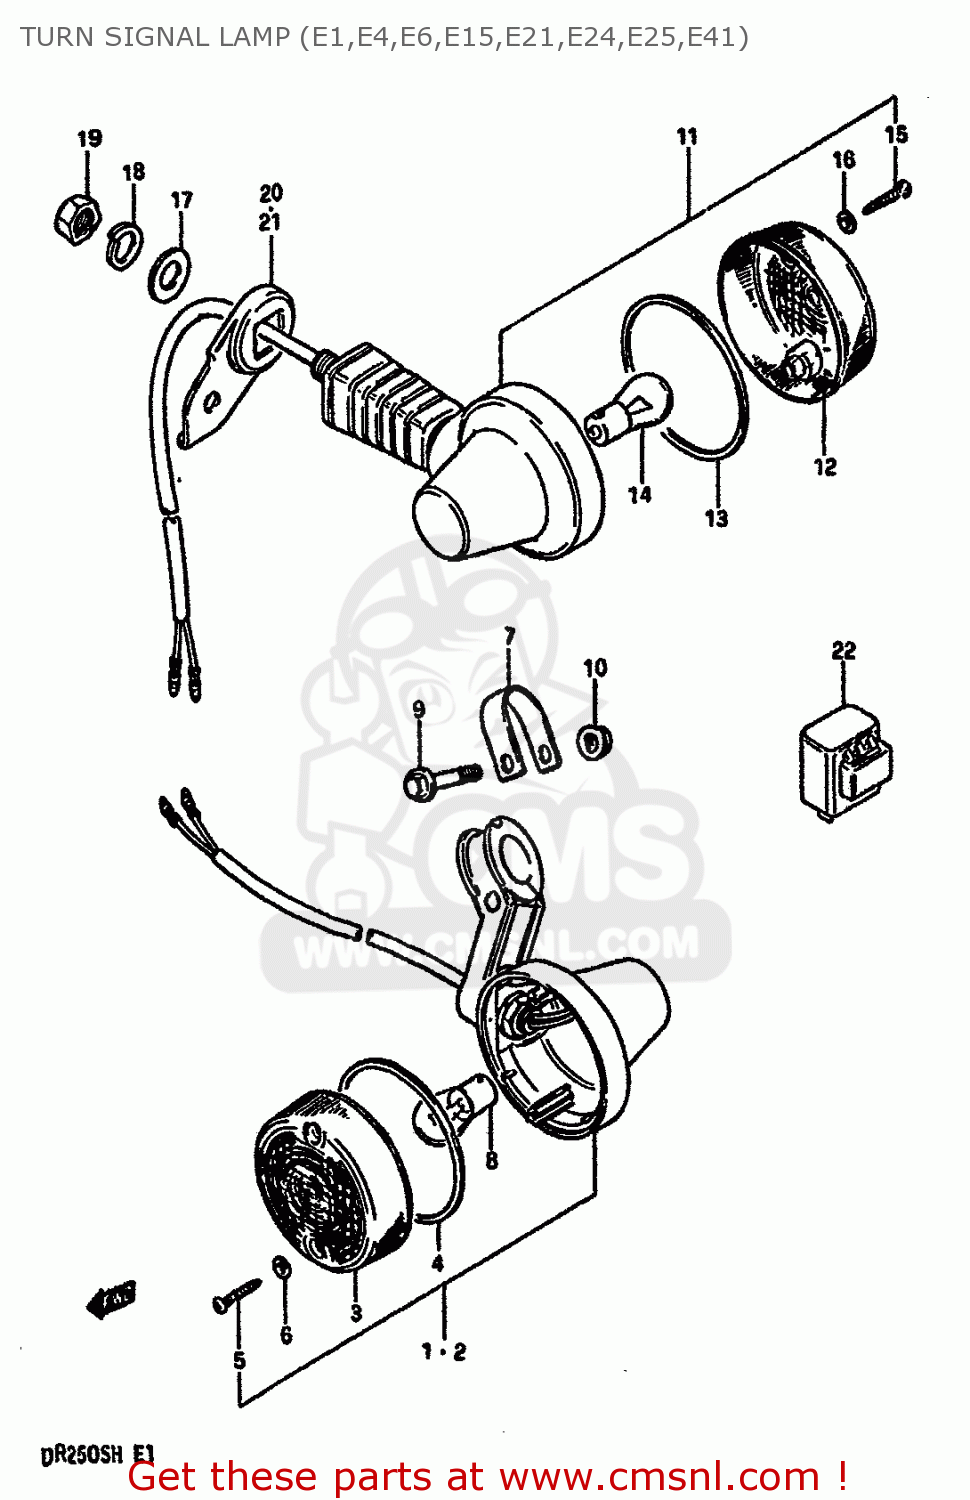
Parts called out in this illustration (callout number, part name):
1	LAMP ASSEMBLY,FRONT TURN SIGNAL
2	LAMP ASSEMBLY,FRONT TURN SIGNAL
3	LENS
4	GASKET (NAS)
5	SCREW TAPP.
6	GASKET (NAS)
7	PLATE
8	BULB 12V 21W
9	BOLT 5X42
10	NUT ,5MM
11	LAMP, REAR TURN SIGNAL
12	LENS
13	GASKET (NAS)
14	BULB 12V 21W
15	SCREW TAPP.
16	GASKET (NAS)
17	WASHER (12.5X26X1.6)
18	WASHER
19	NUT 12MM
20	BRACKET,REAR TURN SIGNAL LAMP
21	BRACKET,RR TURNSIGNAL LAMP,L
22	RELAY,TURN SIGNAL
